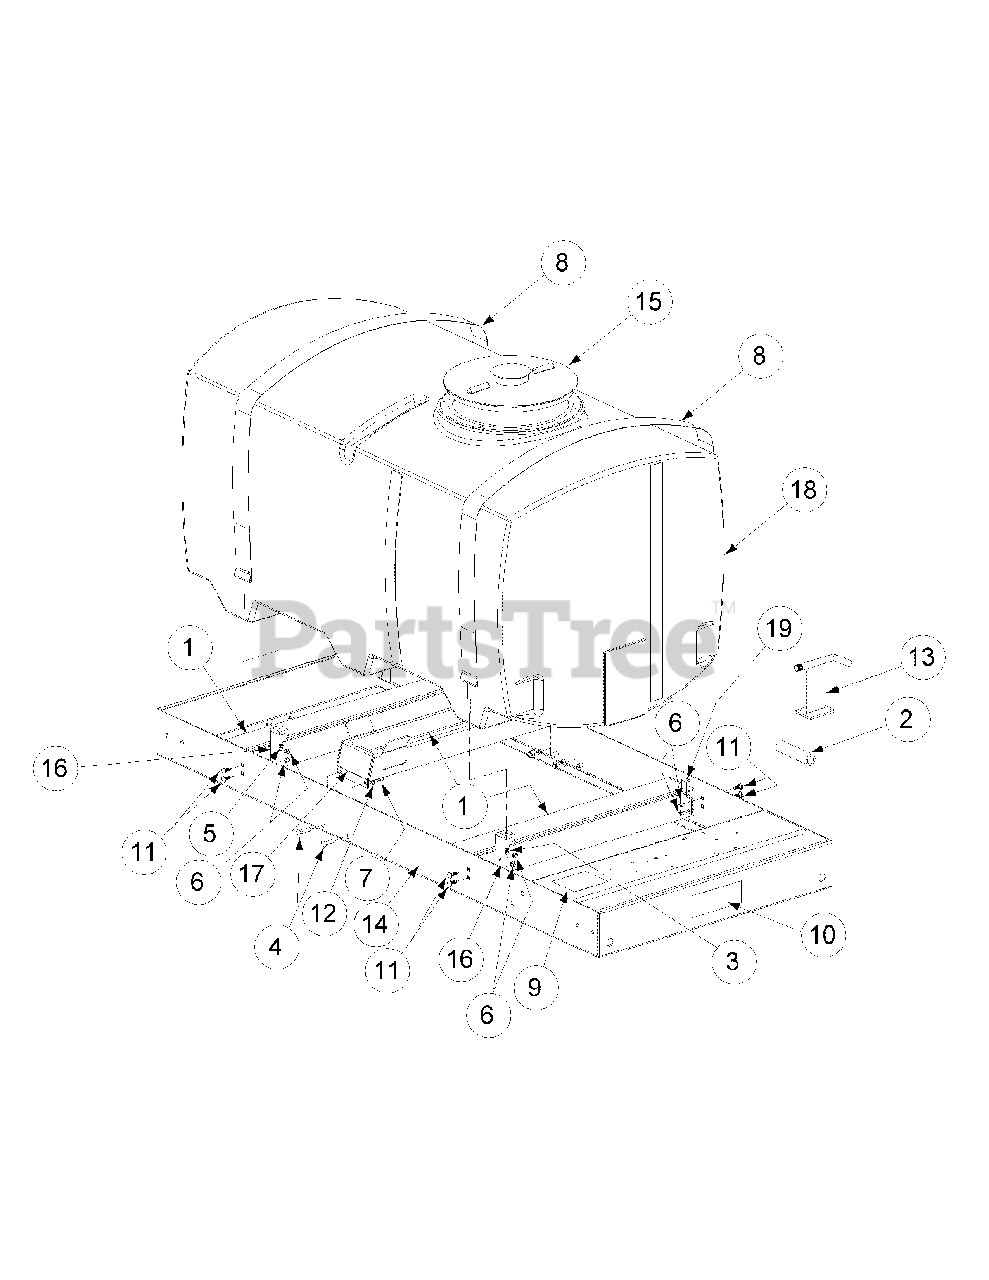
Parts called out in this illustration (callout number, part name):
1	1/4 Foam Back
2	14.5" Hose
3	5/16 Flat Washer
4	1/2-13 x 1-1/2 Hex Cap Screw
5	5/16-18 Nylock Nut
6	Nylock Nut, 3/8-16
7	Lock Nut, Nylon Insert, 1/2-13
8	Tank Strap Assembly
9	Decal, Safety Procedures
10	Decal, Cub Cadet Commercial
11	Carriage Bolt, 3/8-16 x 1
12	Flat Washer, .536 ID x .930 OD x .05
13	Air Gap Filler Kit
14	Main Frame Assembly
15	16" Fillwell Cap w/Center Cap
16	Strap Mounting Bracket
17	Frame Center Support Bracket
18	Rectangular Tank
19	Strap Mounting Hook
